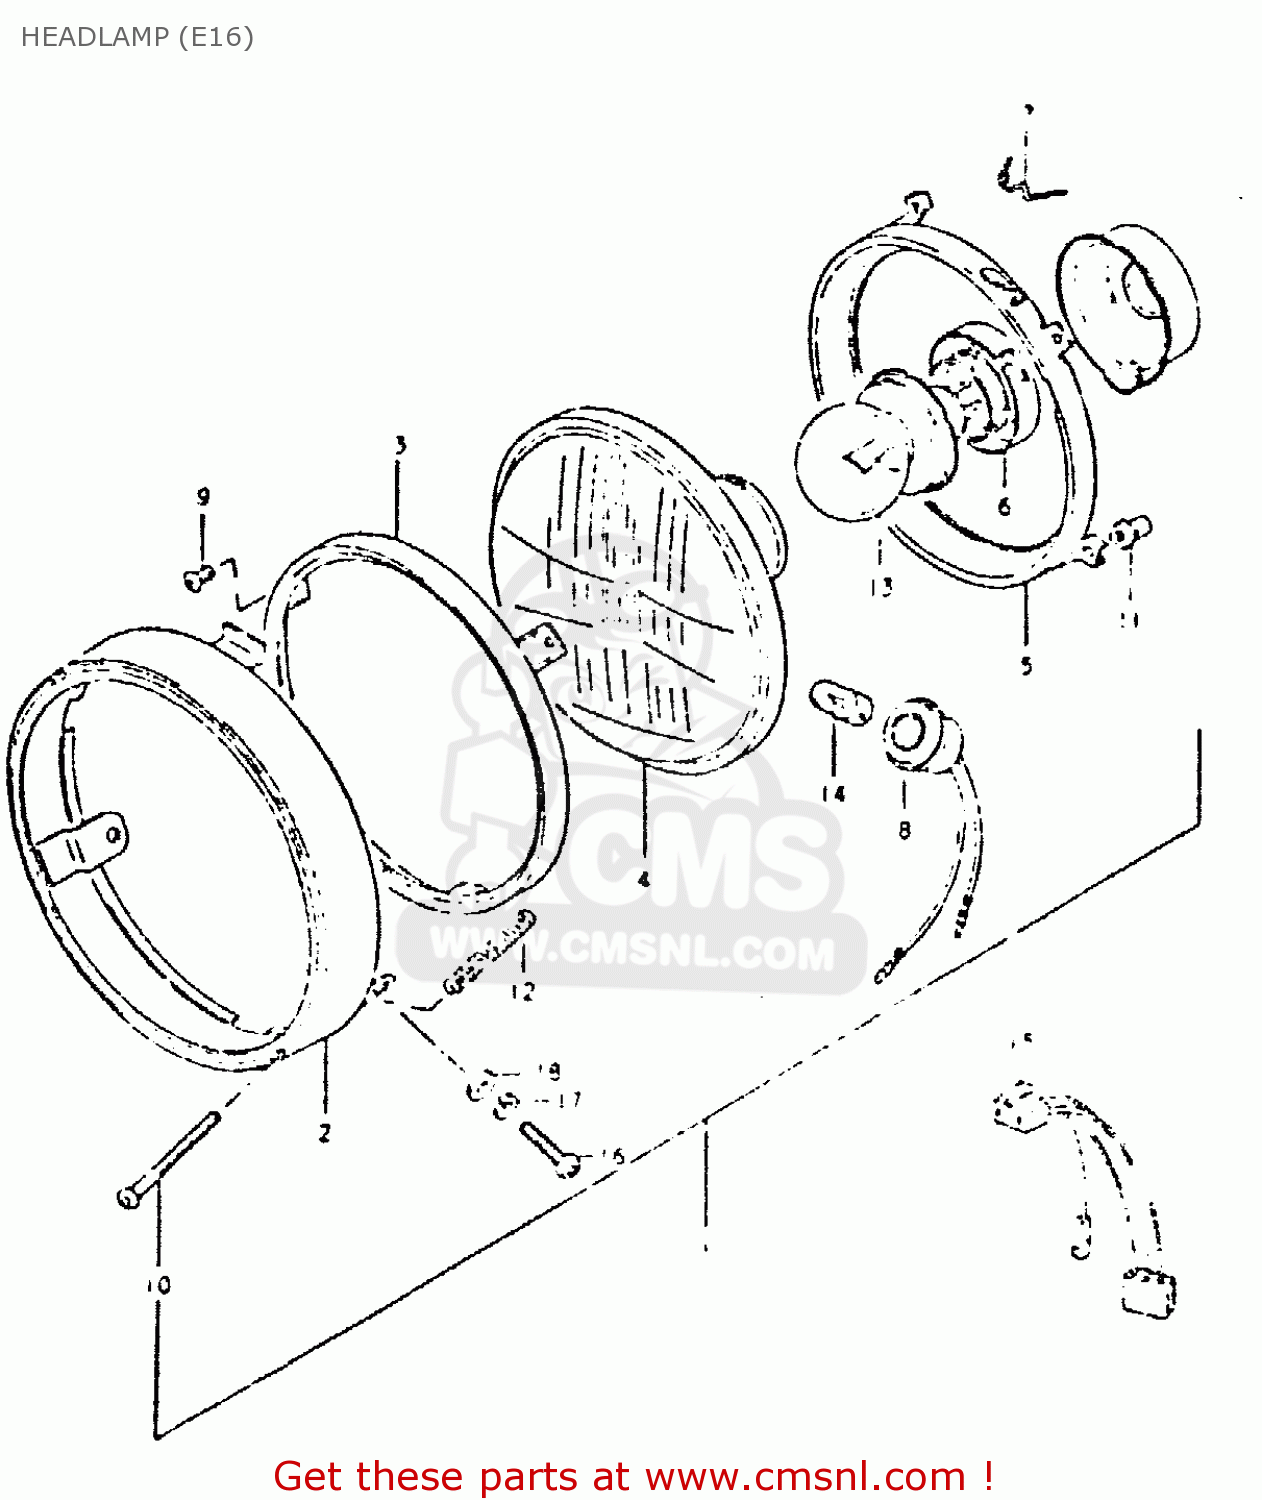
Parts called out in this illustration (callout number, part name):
1	HEADLAMP ASSY
2	RIM
3	RETAINER,HEADLAMP
4	UNIT
5	RING,HEADLAMP UNIT
6	SETTER,BULB
7	SPRING,HEADLAMP UNIT
8	SOCKET
9	SCREW
10	SCREW,HEADLAMP ADJUST
11	NUT,HEADLAMP ADJUSTER
12	SPRING,ADJUSTING
13	BULB (6V,45/40W)
14	BULB(6V4W,STANLEY,A1364J)
15	LEAD WIRE,HEADLAMP
16	SCREW
17	LOCK WASHER
18	WASHER
